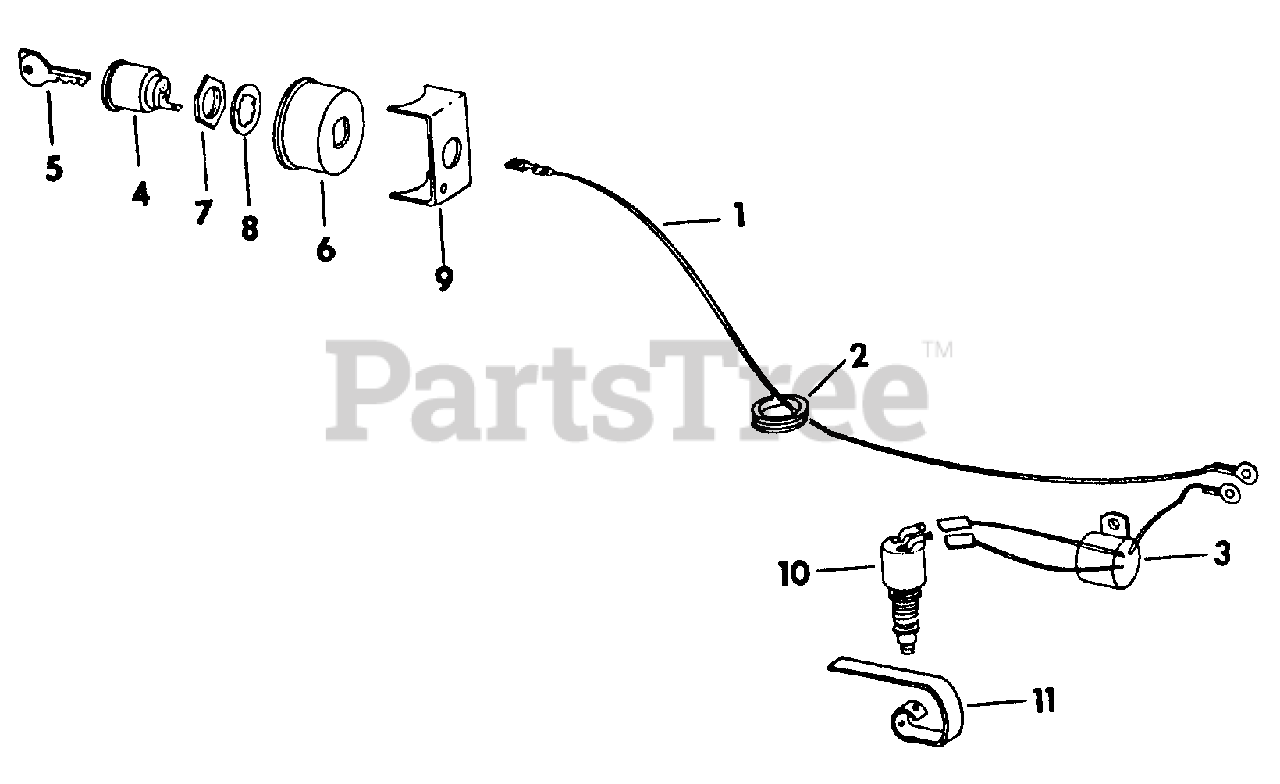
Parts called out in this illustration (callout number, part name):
1	Cable Assy, Magneto Ground
3	Module Assy, Control
4	Switch, Ignition Key
5	Key, Ignition Switch
6	Socket, Ignition Switch
7	Nut, Ignition Switch
8	Washer, Ignition Switch
9	Retainer, Ignition Switch
10	Switch Assy, Neutral Starting
11	Spring, Neutral Start
